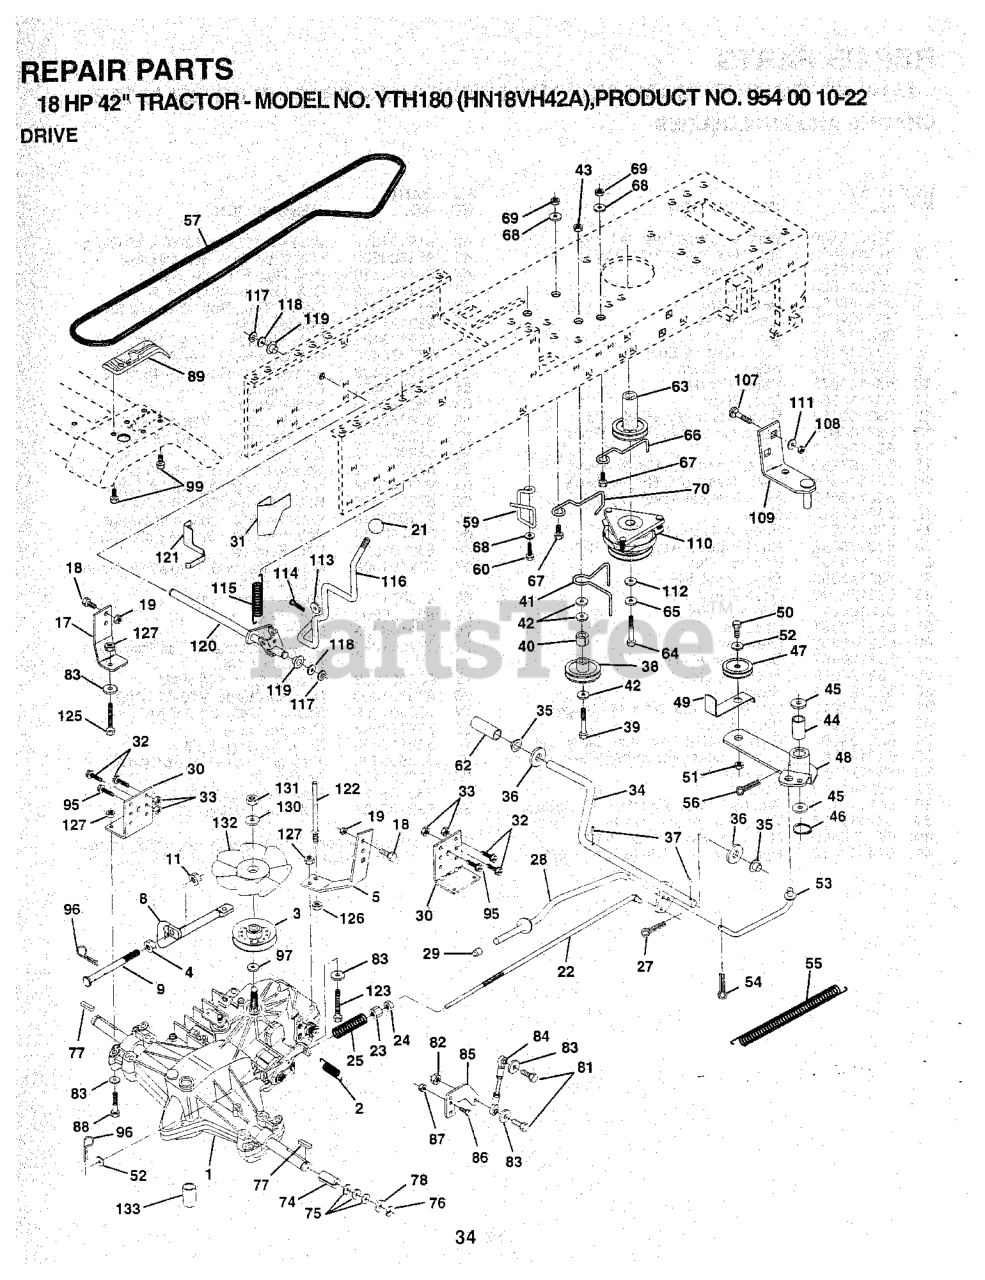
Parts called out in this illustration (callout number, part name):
1	TRANSAXLE ASSY
2	SPRING BRAKE
3	PULLEY TRANSAXLE
4	JAM NUT TI
5	STRAP RH TORQUE
8	BYPASS CONTROL
9	ROD BYPASS
11	NUT.71038.31-18.HEX.NYLOCK
17	STRAP LH TORQUE
19	NUT
21	KNOB.DELUXE.(PISTOL.GRIP).BLAC
22	ROD BRAKE
23	NUT
24	NUT
25	SPRING ROD LT
27	COTTER PIN
28	BRAKE PARK ROD
29	PLUNGER CAP
30	BRACKET TRANSAXLE
31	KEEPER BELT LH
33	NUT.71038.31-18.HEX.NYLOCK
34	SHAFT FOOT PEDAL
35	BEARING.NYLON
37	DRIVE PIN
38	PULLEY.IDLER.FLAT
41	BELT KEEPER LT NLA
42	WASHER
43	NUT
44	BEARING LT (2 2)
47	IDLER PULLEY
49	RETAIN BELT
50	BOLT
52	WASHER
53	LINK, CLUTCH LT
54	COTTER PIN
55	SPRING, RETURN LT
56	COTTER PIN
57	DRIVE BELT, LTH & YTH TRACTORS
59	KEEPER CENTER SPAN
60	SCREW
62	COVER, PEDAL (1 2)
63	PULLEY CLU ELEC
64	BOLT
65	LOCKWASHER
66	KEEPER,BLT ENG LT
67	BOLT
68	WASHER
69	NUT
70	KEEPER BELT ENGLH
74	SPACER SPLIT
77	SQUARE KEY
81	BOLT.5/16-18X1-1/4 FULL.THREAD
82	NUT.71038.31-18.HEX.NYLOCK
83	WASHER M
84	ROD.TIE.BALL.4.75
85	CONTROL ARM
87	NUT.71038.31-18.HEX.NYLOCK
89	CONSOLE
95	SCREW
96	RETAINER M
99	SCREW.HI-LO.CONSOLE
107	RP BOLT 5/16-18 X3/4 ZN/YEL GR
108	LOCKNUT
109	BRACKET ASM MTG
110	CLUTCH.ELECT.CVX.105 FT/LB.
113	WASHER
114	PIN COTTER
115	SPRING,TORSION
119	BUSHING.STEERING.ROD LTB-WSL
120	SHAFT ASSY
121	KEEPER BELT LH
122	KEEPER BELT RH
123	BOLT.FIN HEX 5/16-18UNC X2 1/4
125	HEX BOLT
127	NUT.71038.31-18.HEX.NYLOCK
132	FAN 7" HYDRO
133	LINE FUEL HYD 4"
